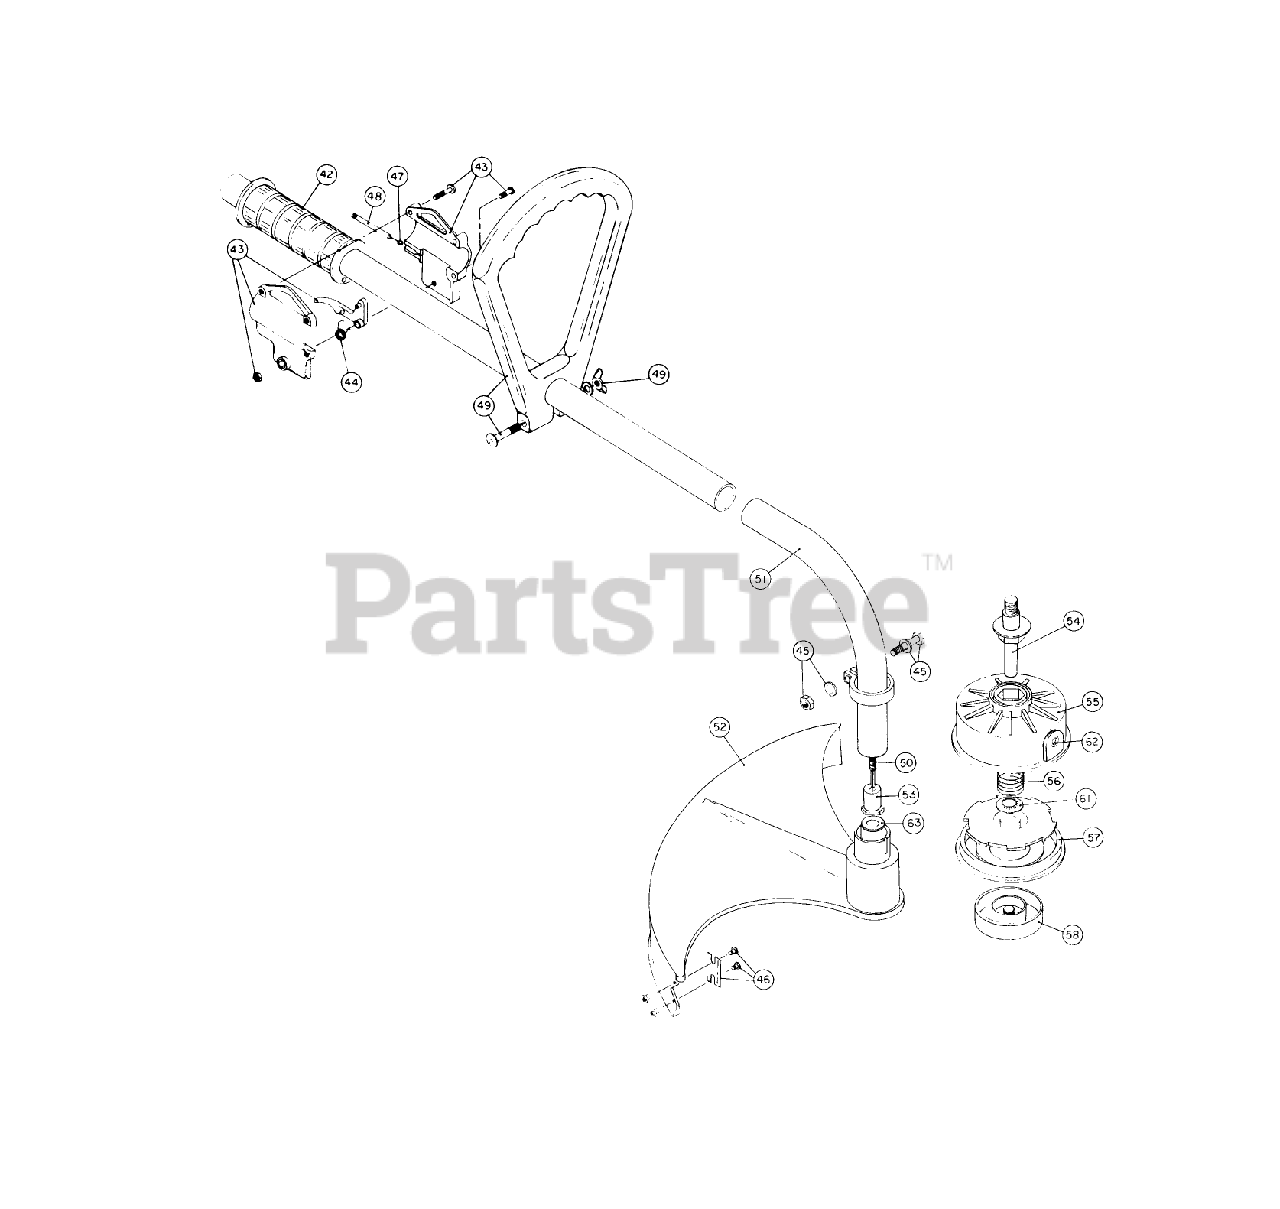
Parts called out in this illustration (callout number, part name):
44	THROTTLE TRIGGER SPRING
46	BLADE ASM
47	THROTTLE CABLE WIRE
48	THROTTLE CABLE HSG
53	SQUARE DRIVE NUT
57	REEL - INNER
61	RETAINER WASHER
